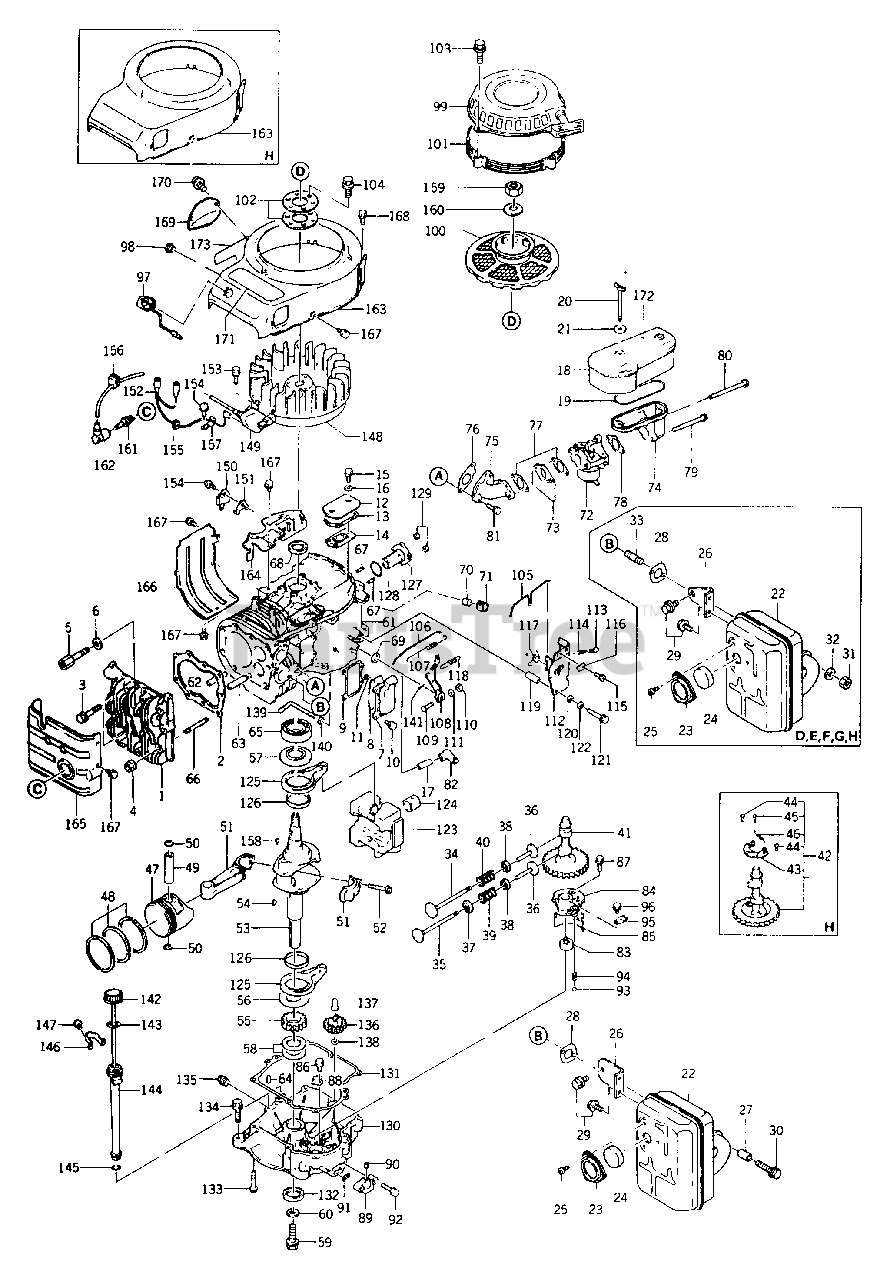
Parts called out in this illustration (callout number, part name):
1	HEAD, cylinder
2	GASKET, head
3	BOLT (10x55)
4	NUT (10mm)
6	WASHER
7	COVER, valve chamber
9	GASKET
10	BOLT (6x16)
11	SCREW
15	BOLT
16	GASKET
18	AIR FILTER ASSY
19	GASKET
21	WASHER
22	MUFFLER ASSY
23	CAP
24	ARRESTER, spark
25	SCREW (5x8)
27	COLLAR
28	GASKET
29	BOLT (8x12)
31	NUT (8mm)
32	WASHER
33	STUD
34	VALVE, intake
35	VALVE, exhaust
38	RETAINER, spring
39	SPRING, valve
40	SPRING, valve
41	SHAFT, cam
42	CAM SHAFT COMP
43	DECOMPRESSOR
44	PIN
45	PIN
46	SPRING
47	PISTON
48	PISTON RING SET
49	PIN, piston
50	RING, snap
51	CONNECTING ROD ASSY
52	BOLT, connecting rod
53	CRANK SHAFT COMP
55	GEAR, helical
58	SHIM
61	CRANK CASE COMP
62	GUIDE, valve (IN)
63	GUIDE, valve (EX)
65	BEARING, ball (6207)
71	CLIP
72	CARBURETOR ASSY
74	PIPE, intake
75	PIPE, intake
76	GASKET
77	GASKET
78	GASKET
80	BOLT
81	BOLT (8x25)
83	OIL PUMP ASSY
84	PUMP COVER COMP
85	FILTER, oil
86	BOLT (5x8)
87	BOLT (8x25)
92	BOLT (8x30)
93	BALL, steel
95	PLATE
96	BOLT (6x10)
98	GROMMET
99	RECOIL STARTER ASSY
103	BOLT (6x35)
104	BOLT (8x12)
105	LINK, choke
106	LINK
108	GOVERNOR ARM COMP
110	NUT (6mm)
111	WASHER
112	CONTROL PANEL ASSY
113	SCREW (4x25)
114	SPRING
115	BOLT
120	WASHER
121	BOLT (6x50)
122	WASHER, spring
123	WEIGHT COMP
124	BEARING, plane
125	ROD ASSY
126	BEARING, plane
127	SHAFT
129	NUT
130	CRANK CASE COVER COMP
131	GASKET
133	BOLT (8x45)
134	BOLT (8x25)
136	GOVERNOR ASSY
137	SLEEVE
138	WASHER
139	ARM, pivot
140	WASHER
141	PIN, snap
143	GASKET
145	O-RING
146	CLAMP
147	BOLT (5x8)
148	FLYWHEEL COMP
149	COIL, ignition
150	IGNITER
151	BRACKET
152	WIRE, lead
153	BOLT (5x25)
154	SCREW (4x8)
157	CLAMP
159	NUT (18mm)
161	PLUG, spark (BMR 4A)
162	CAP, spark plug
163	HOUSING, fan
164	HOUSING, fan
167	BOLT (6x10)
168	BOLT (6x14)
169	COVER
170	SCREW (4x8)
171	LABEL, brand
172	LABEL, manual
173	LABEL, manual
